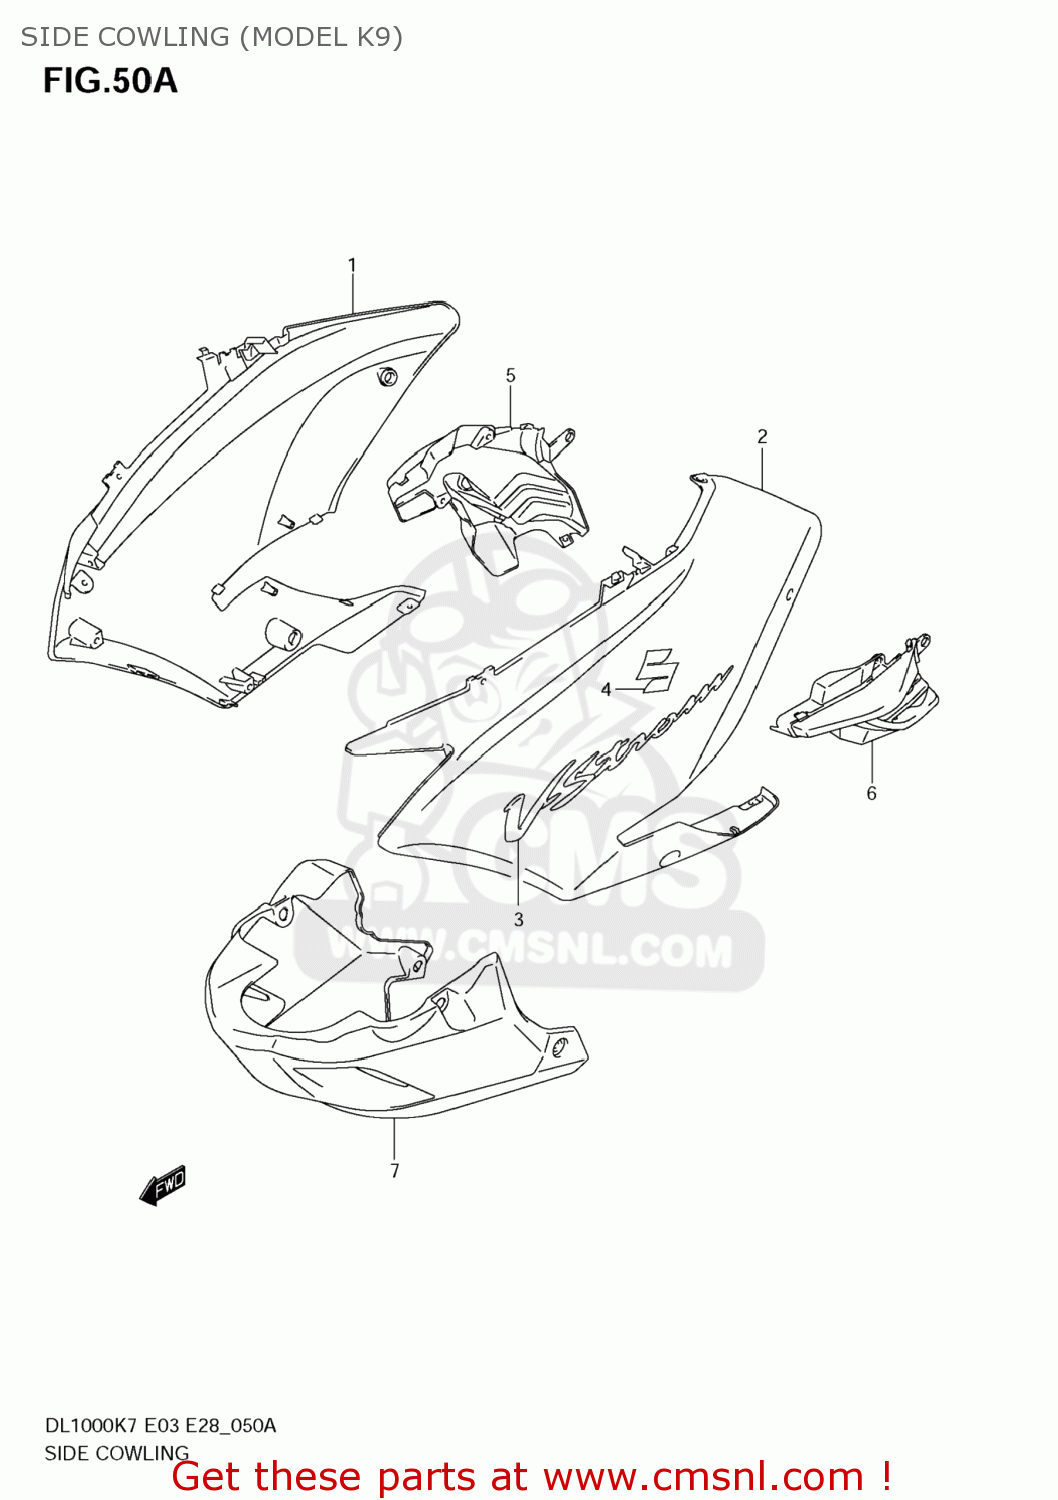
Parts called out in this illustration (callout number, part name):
1	COWLING ASSY,SIDE,R
2	COWLING ASSY,SIDE,L
3	EMBLEM,COWLING SIDE
4	EMBLEM,S
5	COVER,SIDE COWL,R(BLACK)
6	COVER,SIDE COWL,L(BLACK)
7	COWLING,UNDER
